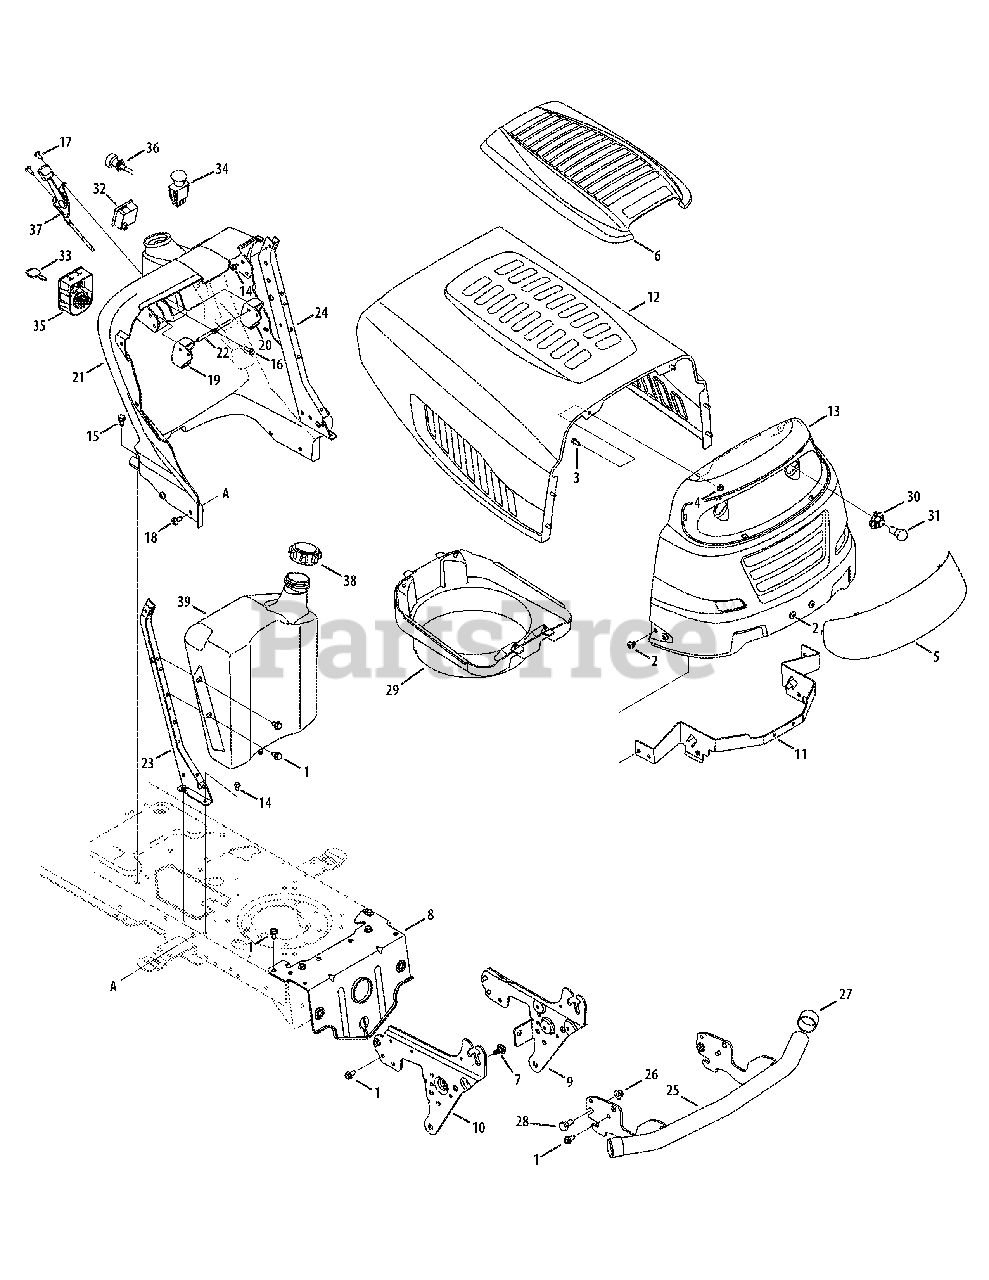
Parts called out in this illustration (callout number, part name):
1	Screw, 5/16-18 x .750
2	Screw, 5/16-18 x .375
3	Hex Cap Screw, 1/4-20 x.62
4	Flange Lock Nut, 1/4-20
5	Headlight Lens
6	Hood Cover, 5 Style
7	Shoulder Screw,.43 x.29
8	Pivot Bar Bracket
9	Pivot Support Bracket LH
10	Pivot Support Bracket RH
11	Hood Pivot Bracket
12	5-Style Hood
13	1-Style Grille
14	Self-tapping Screw, 1/4-20 x.5
15	Screw, 5/16-18 x .500
16	Self-tapping Screw, 1/4-15 x.75
17	Screw, 1/4-14 x.625
18	Screw, 5/16-18 x.75
19	Cruise Control Button
20	Parking Brake Button
21	Dash Panel
22	Brake/Cruise Pivot Rod
23	RH Dash Support Plate
24	LH Dash Support Plate
25	Bumper Assembly
26	Flange Lock Nut, 3/8-16
28	Shoulder Bolt, 3/8-16
30	Headlight Socket
32	Systems Ind. Monitor w/Hr. Mtr.
33	Ignition Key w/ plastic cover
34	Electric PTO Switch
35	Ignition Switch
36	Choke Control Cable
37	Throttle Control/Cable
38	Fuel Cap
39	Fuel Tank, Three Gallon
